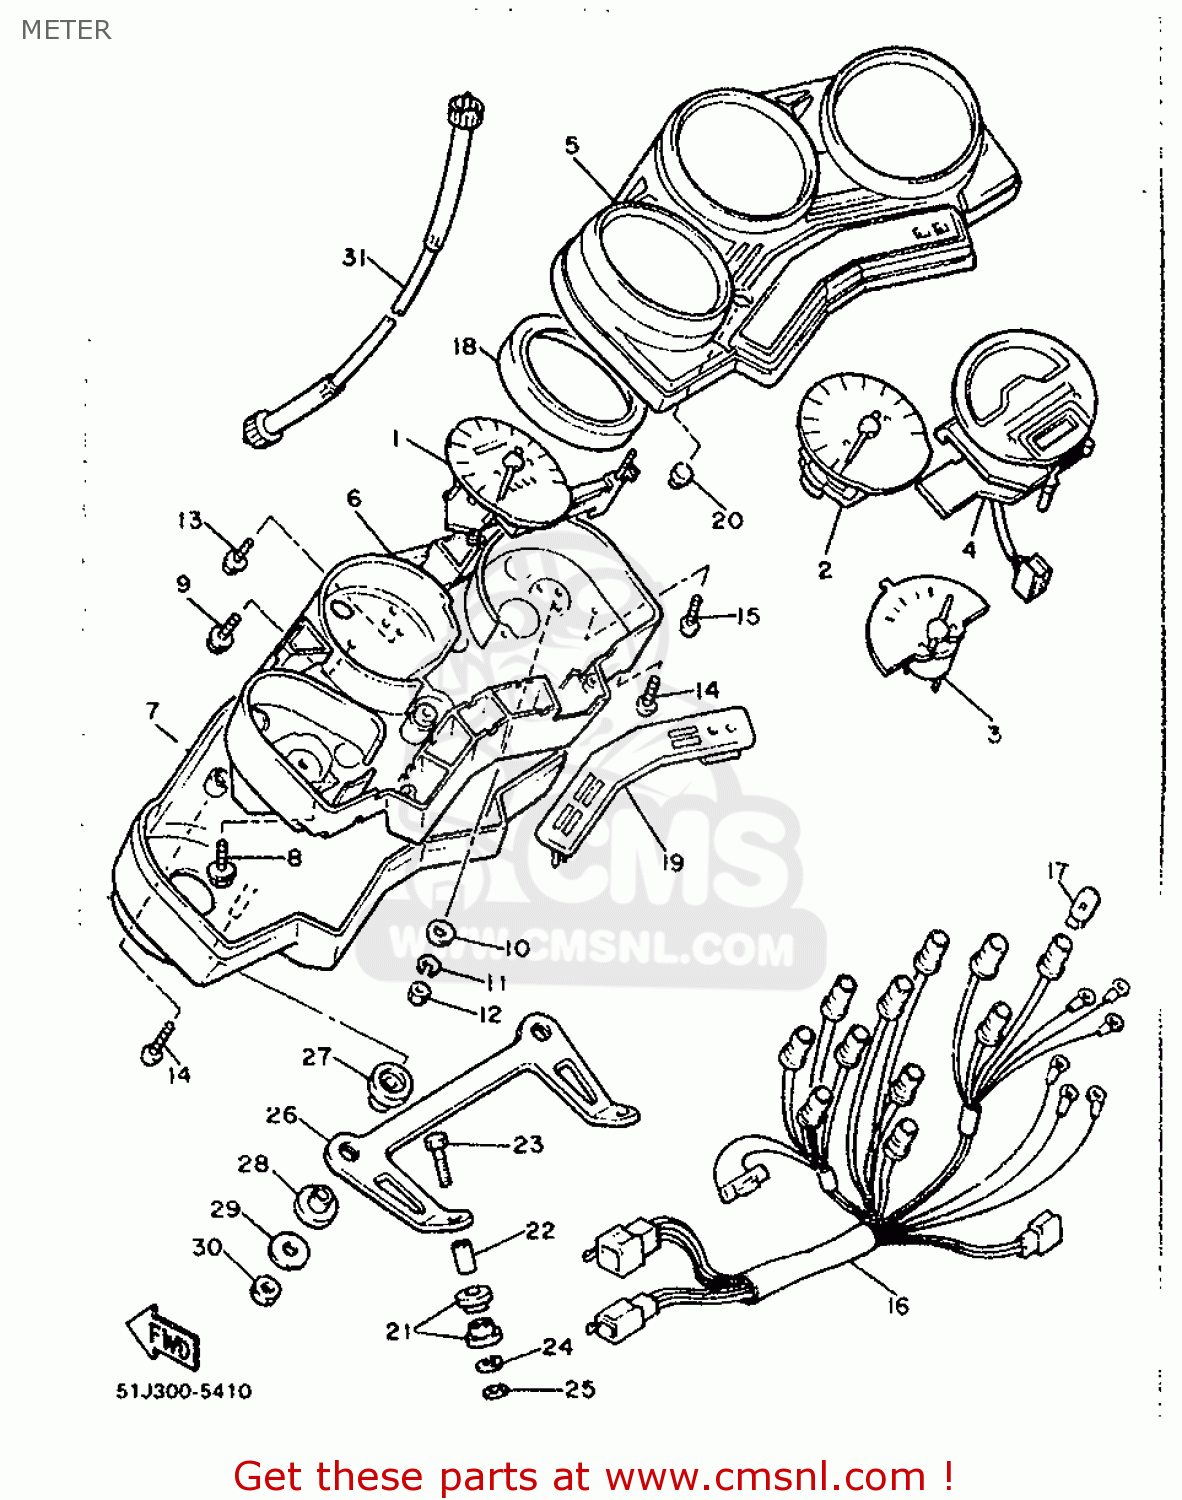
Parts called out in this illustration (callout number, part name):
01	SPEEDOMETER ASSY
02	TACHOMETER ASSY
03	FUEL METER ASSY
04	PRINT BOARD ASSY
05	CASE, UPPER
06	CASE, INNER
07	COVER, METER
08	SCREW, PAN HEAD (31A)
09	SCREW, WITH WASHER (5G2)
10	WASHER (J10)
11	WASHER, SPRING
12	NUT (6G8)
13	SCREW, WITH WASHER (5G2)
14	SCREW, TAPPING (5G2)
15	SCREW, TAPPING (16G)
16	SOCKET CORD ASSY
17	BULB (T-10 12V 3.4W)
18	REFLECTOR
19	PANEL ASSY
20	KNOB, TRIP METER
21	DAMPER, METER BRACKET
22	COLLAR (877)
23	BOLT(2GU)
24	WASHER,SPRING
25	WASHER, PLATE (838-77728-00)
26	BRACKET, METER
27	DAMPER
28	DAMPER
29	WASHER, PLATE
30	NUT, CROWN(1FN)
31	SPEEDOMETER CABLE ASSY
